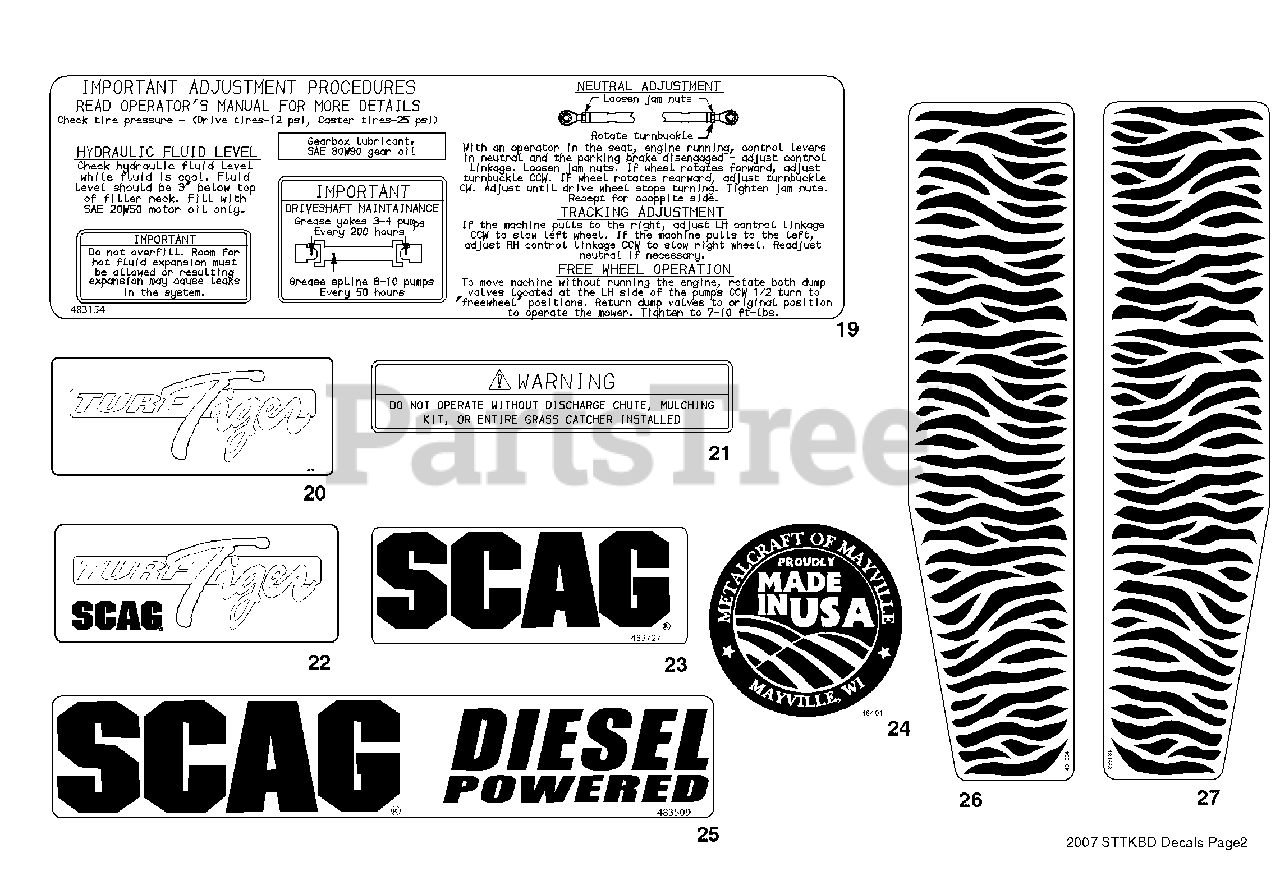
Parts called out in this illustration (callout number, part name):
19	Decal, Checks and Adjustments
20	Decal, Turf Tiger
21	Decal, Warning
22	Decal, Turf Tiger
23	Decal, Scag Logo
24	Decal, Metalcraft-Made In USA
25	Decal, Scag Diesel Powered
26	Decal, Stripes-RH
27	Decal, Stripes-LH
